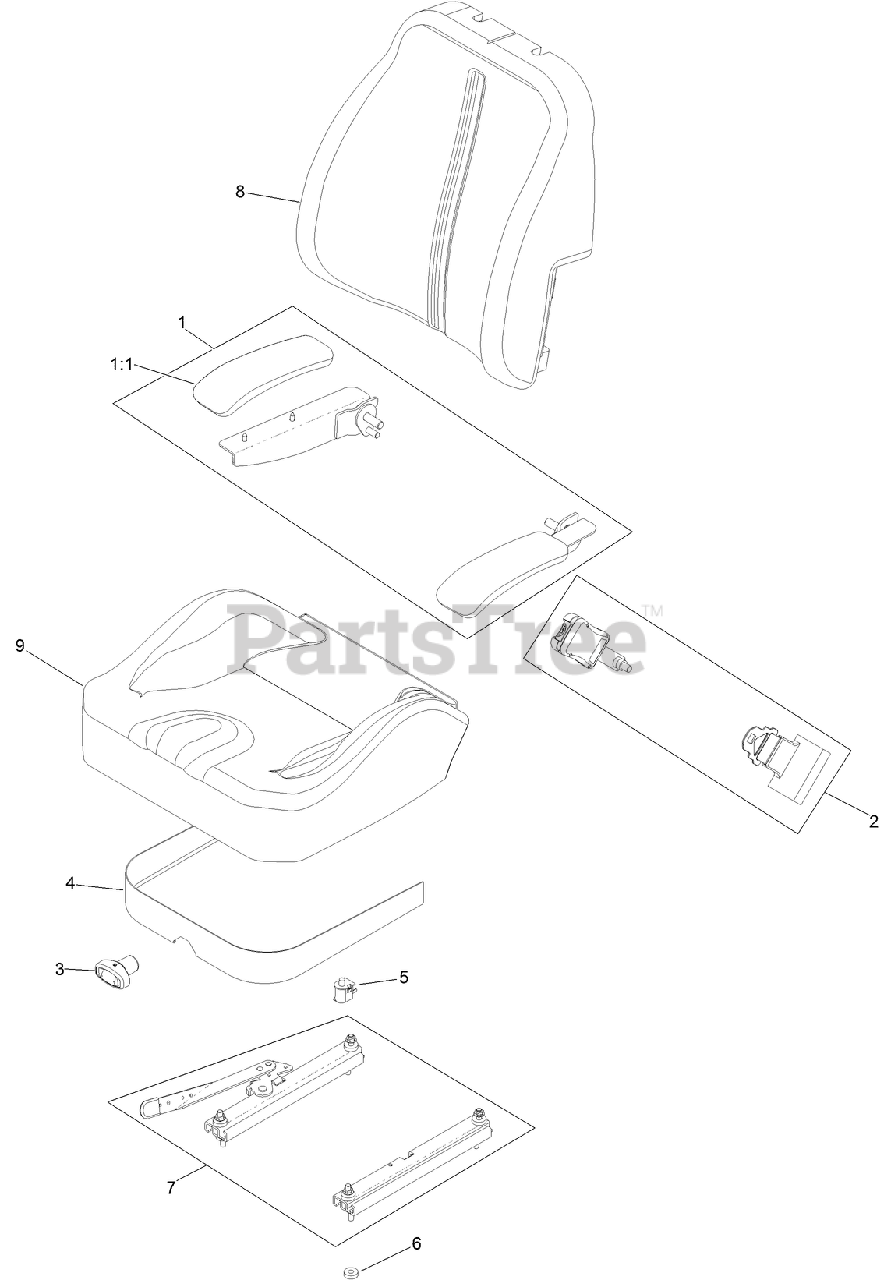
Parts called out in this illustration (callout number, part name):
1	ARMREST KIT
1:1	CUSHION-REST, ARM
2	SEAT BELT KIT
3	KNOB-ADJUSTER
4	COVER-SKIRT W/FASTENERS
5	SWITCH-BAIL
6	SPACER-PIN, MOUNTING
7	TRACK SET
8	COVER-BACK, SEAT
9	COVER-SEAT, BOTTOM
